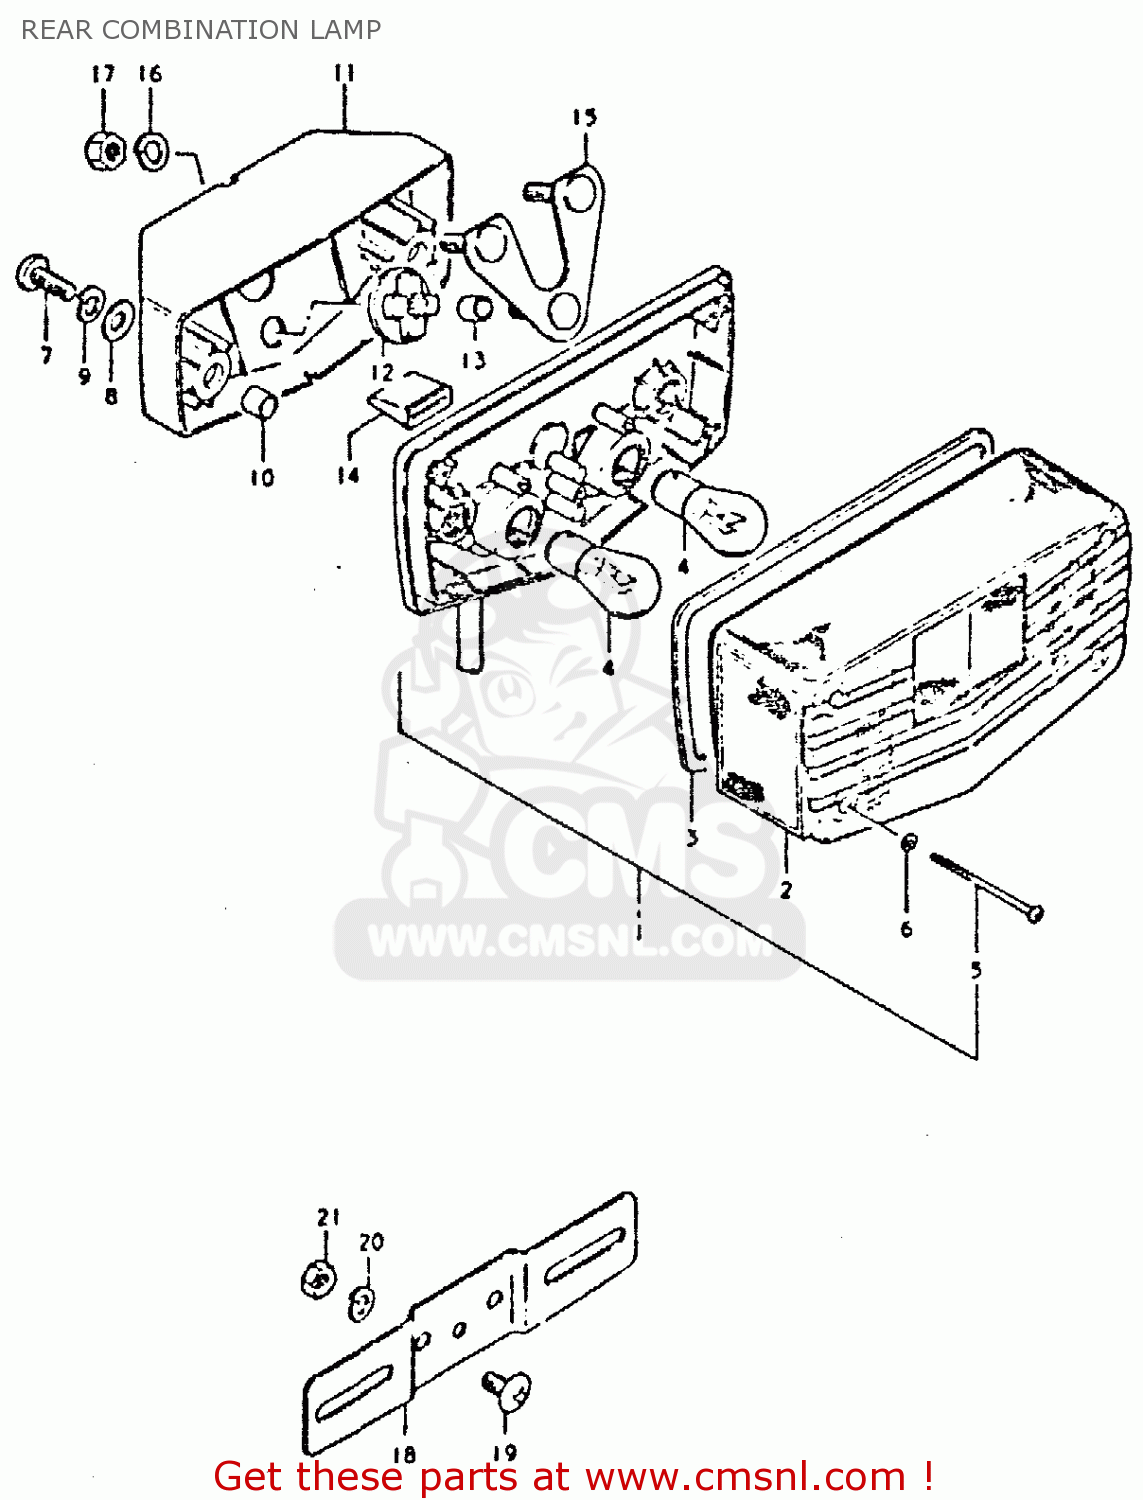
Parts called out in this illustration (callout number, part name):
1	LAMP UNIT, TAIL
2	LENS
3	GASKET,REAR COMBINATION LAMP LENS (NAS)
4	BULB 12V21/5W
5	SCREW
6	GASKET (NAS)
7	SCREW
8	WASHER
9	LOCK WASHER
10	SPACER,REAR COMBINATION LAMP
11	BRACKET UNIT,TAIL LAMP
12	CUSHION,REAR COMBINATION LAMP
13	SPACER,REAR COMBINATION LAMP
14	CUSHION,REAR COMBINATION LAMP
15	PLATE,REAR COMBINATION LAMP
16	LOCK WASHER
17	NUT
18	PLATE,RR LICENSE
19	SCREW
20	LOCK WASHER
21	NUT
